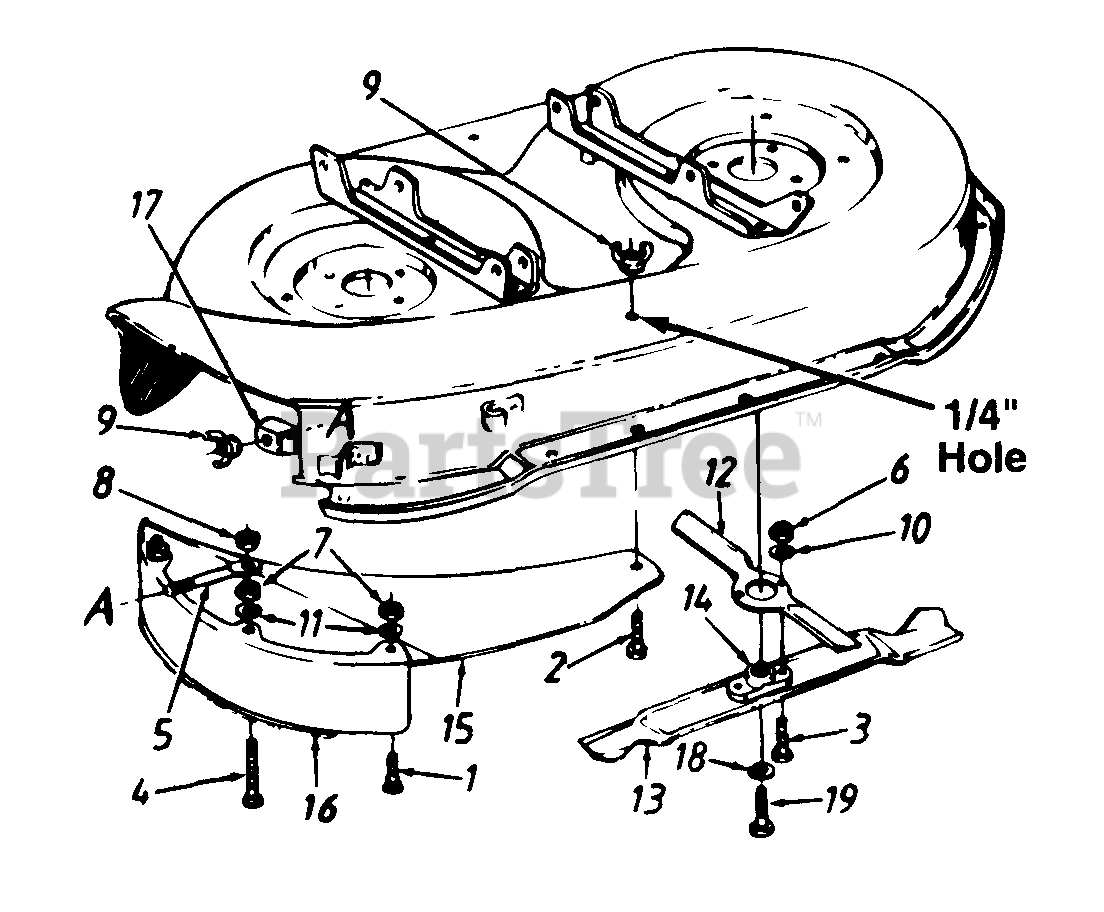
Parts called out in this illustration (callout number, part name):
1	Carriage Bolt 1/4-20 x .62" Lg.
2	Hex Bolt 1/4-20 x 1" Lg.
3	Hex Bolt 7/16-20 x 1.25" Lg. (Gr. 5)
4	Carriage Bolt 1/4-20 x 1" Lg.
5	Retaining Bolt
6	Hex Nut 7/16-20 Thd.
7	Hex Nut 1/4-20 Thd.
8	Hex L-Nut 1/4-20 Thd.
9	Wing Nut
10	L-Wash. 7/16" I.D.
11	L-Wash. 1/4" I.D.
12	Mulching Blade 12.5"
13	Mulching Blade 19.38" (096)
14	Blade Adapter
15	Top Mulching Baffle (096)
16	Side Mulching Baffle (096)
18	L-Wash. 3/8" I.D.
19	Hex Bolt 3/8-24 x 1" Lg. (Gr. 8)
